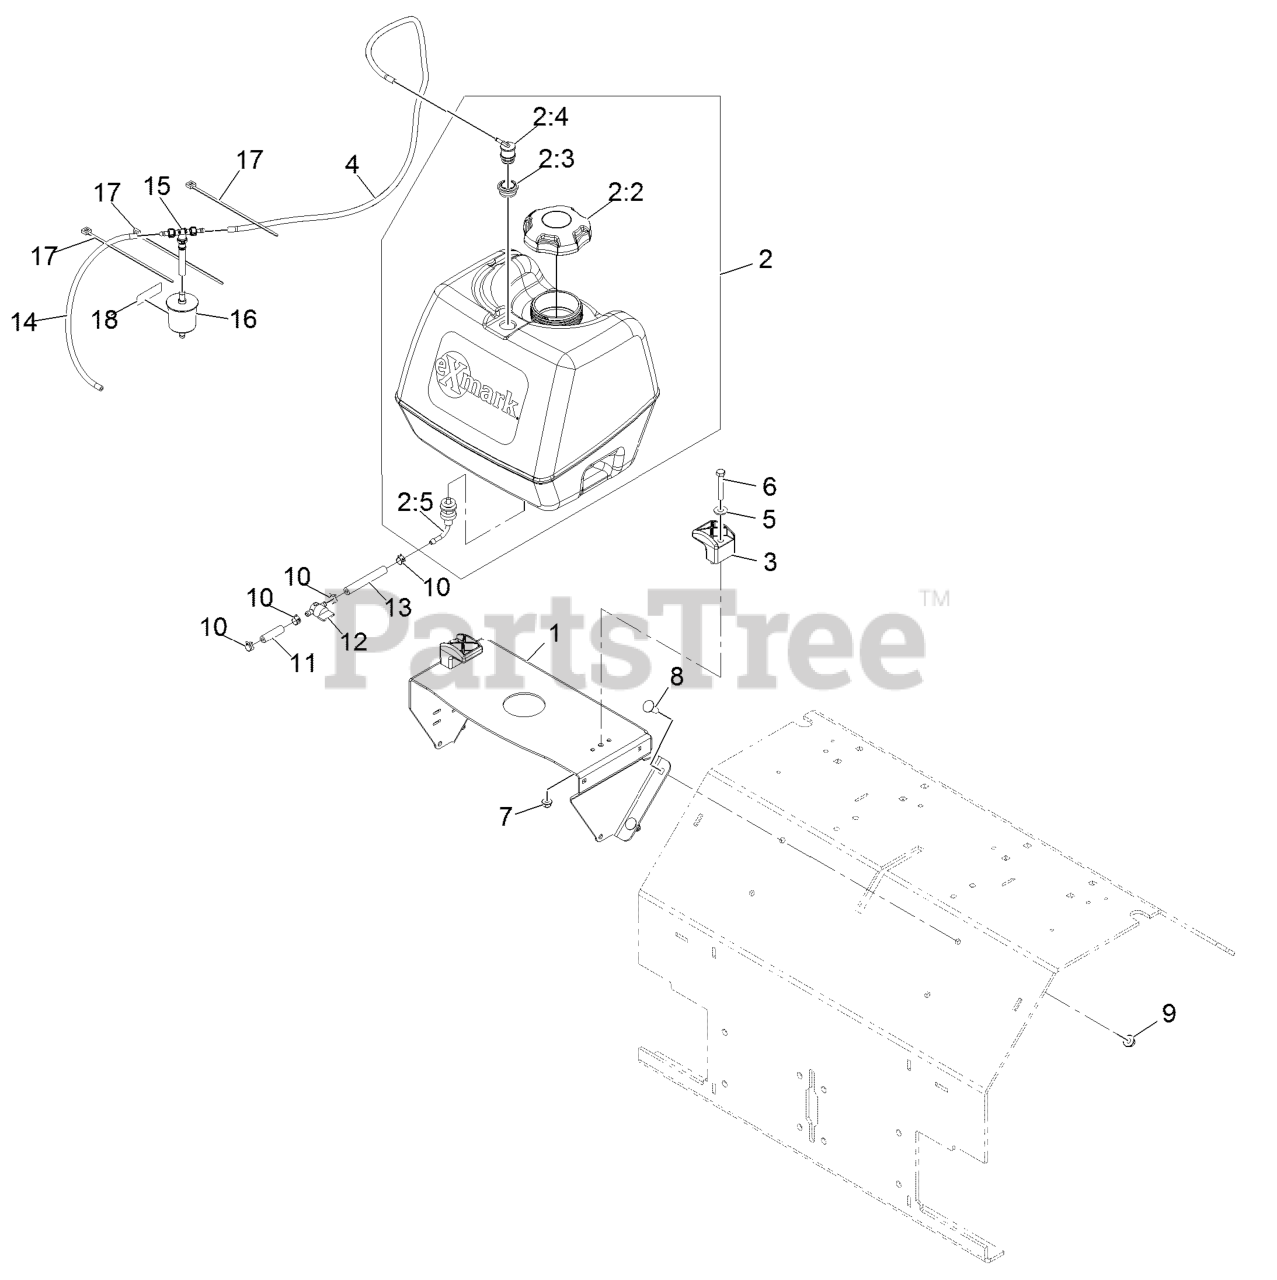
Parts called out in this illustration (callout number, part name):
1	SUPPORT-TANK, FUEL
2	ASM, FUEL TANK
2:3	GROMMET
2:4	VALVE-VENT, FUEL
2:5	FITTING-FUEL, BULKHEAD
4	HOSE-EMISSIONS
5	WASHER-FLAT
6	SCREW-HH
7	NUT-HF, NI
8	SCREW-CARR
9	NUT-HF, NI
10	CLAMP-HOSE
11	HOSE-FUEL
12	VALVE-FUEL
13	HOSE-FUEL
14	HOSE-FUEL
15	TEE AND CHECK
16	FILTER-FUEL
17	TIE-PLASTIC
18	DECAL-FILTER, EMISSIONS
